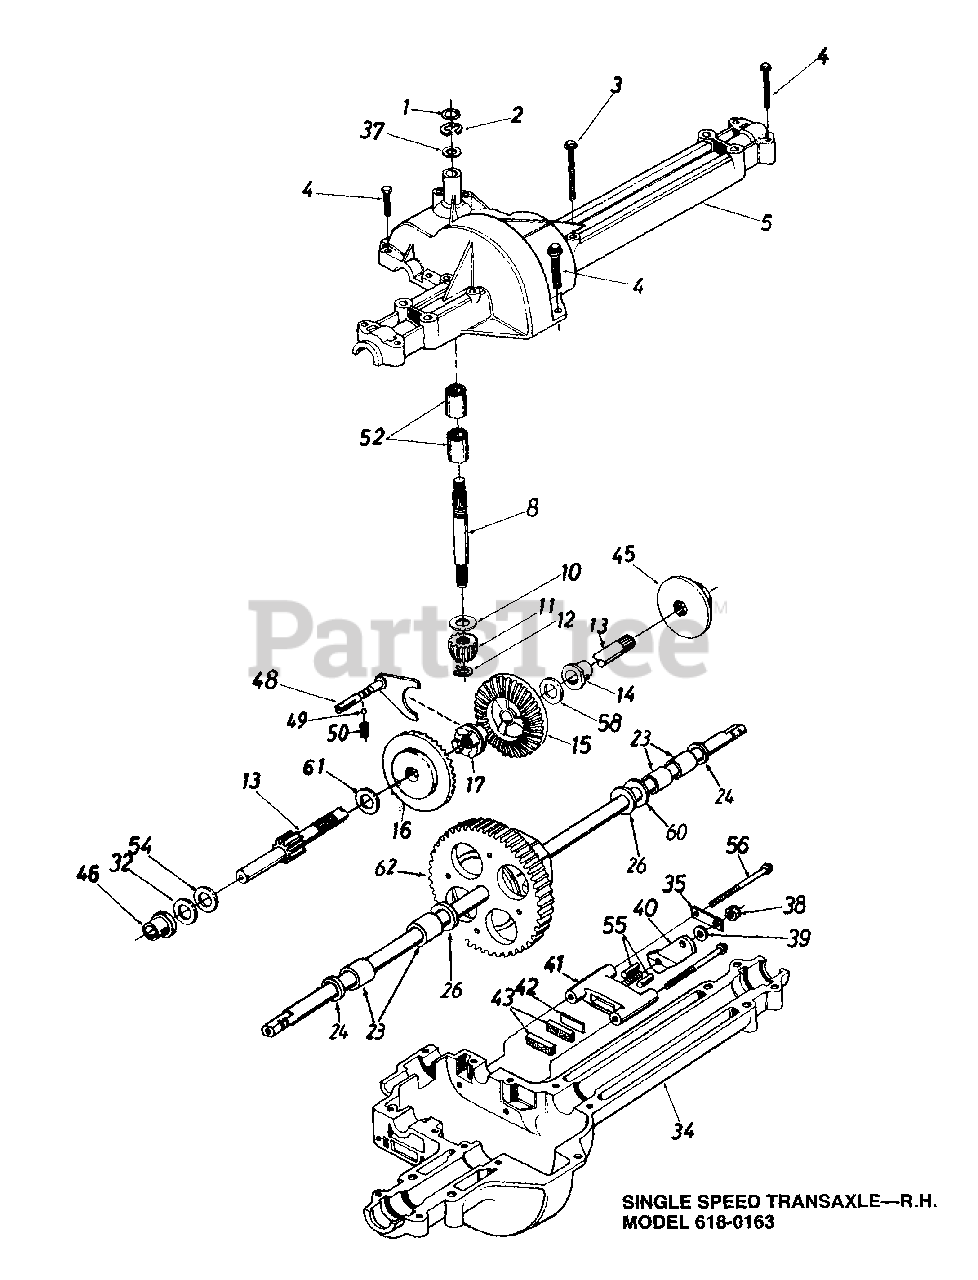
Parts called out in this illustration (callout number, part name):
3	Hex Wash. TT-Tap Scr. 1/4-20 x 1.75" Lg.
4	Hex Tap Scr. 1/4-20 x 1.25" Lg.
5	Upper Housing
10	Thrust Washer 5/8" I.D. x 1.25" O.D.
11	Pinion Input 14T
12	Retaining Ring
13	Drive Shaft - R.H. Brake
14	Flange Brg. 5/8" I.D. x 3/4" Lg.
15	Bevel Gear 42T Small I.D.
16	Bevel Gear 42T Large I.D.
17	Clutch Collar
23	Sleeve Bearing 3/4" I.D. x 1.0" Lg.
24	Oil Seal 3/4" I.D.
26	Fl-Wash. .760" I.D. x 1.5" O.D.
32	Washer
34	Lower Housing
35	Anti-Rotation Brkt.
37	Washer
38	Hex Nut 5/16-24 Thd.
39	Fl-Wash. .344" I.D. x .875" O.D.
40	Actuating Arm
41	Brake Yoke
42	Puck Plate
43	Brake Puck
46	Flange Bearing 5/8" I.D. x 15/16" Lg.
48	Shift Fork Ass'y.
49	Ball Detent .250" Dia.
50	Spring Detent
52	Needle Brg. 5/8" I.D. x 1/2" Lg.
54	Fl-Wash. 5/8" I.D. x 1" O.D. x .020 Thk.
55	Actuating Pin 5/16" Dia.
56	Hex Wash Hd. Self-Tap Scr. 1/4-20 Thd.
58	Fl-Wash. 5/8" I.D. x 1" O.D. x .020 Thk.
60	Washer
61	Thrust Washer
62	Differential Ass'y.
